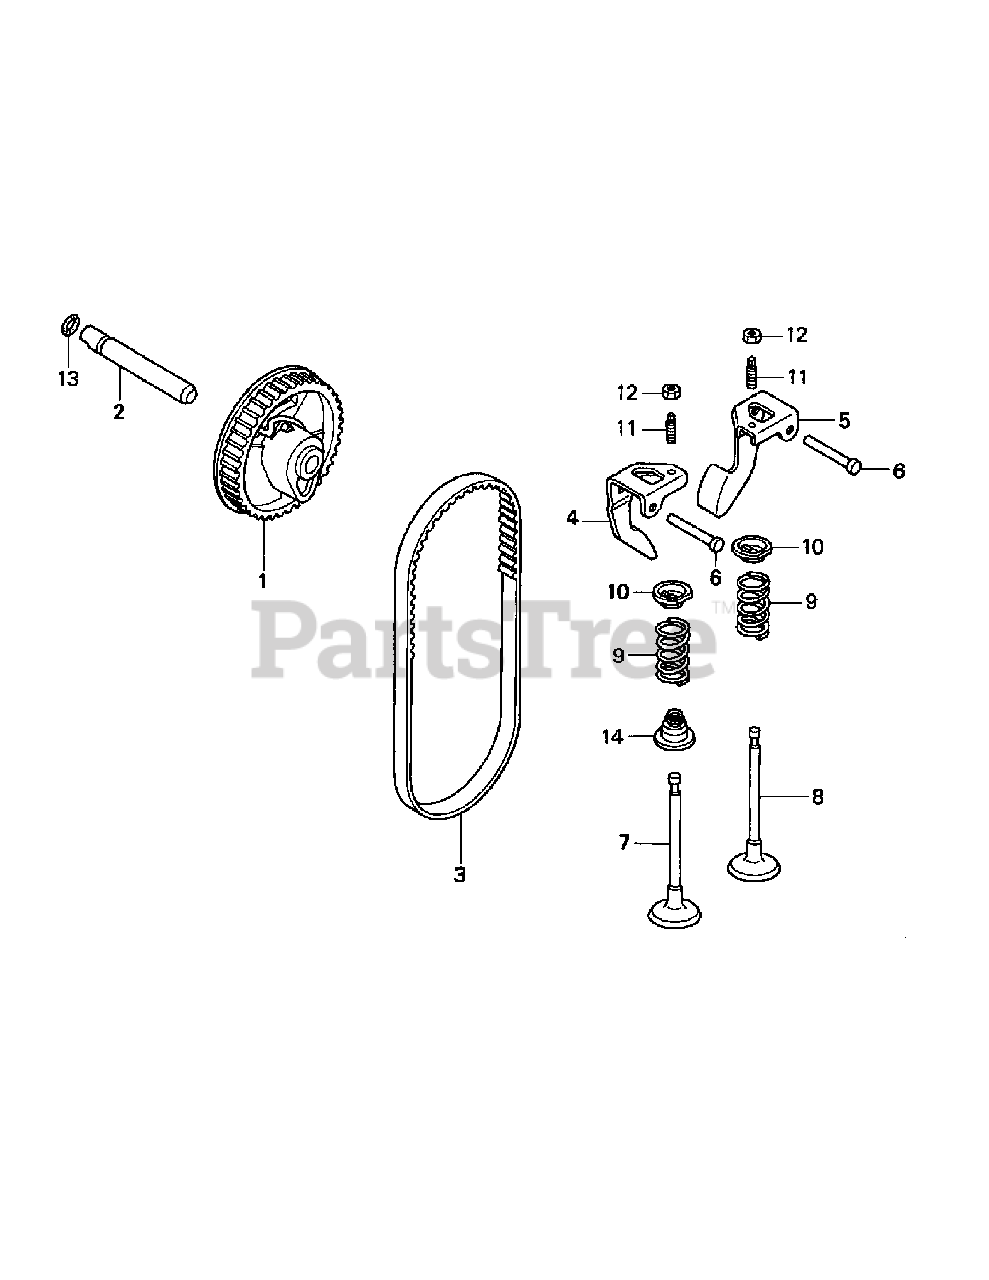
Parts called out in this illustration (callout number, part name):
1	Camshaft Pulley
2	Cam Pulley Shaft
3	Timing Belt, 84HU7 G-200
4	Internal Valve Rocker Arm
5	External Valve Rocker Arm
6	Rocker Arm Shaft
7	Internal Valve
8	External Valve
9	Valve Spring
10	Internal Valve Spring Retainer
11	Tappet Adjustable Screw
12	Tappet Adjutable Nut
13	O-Ring, 6.8 x 1.9
14	Valve Stem Seal
